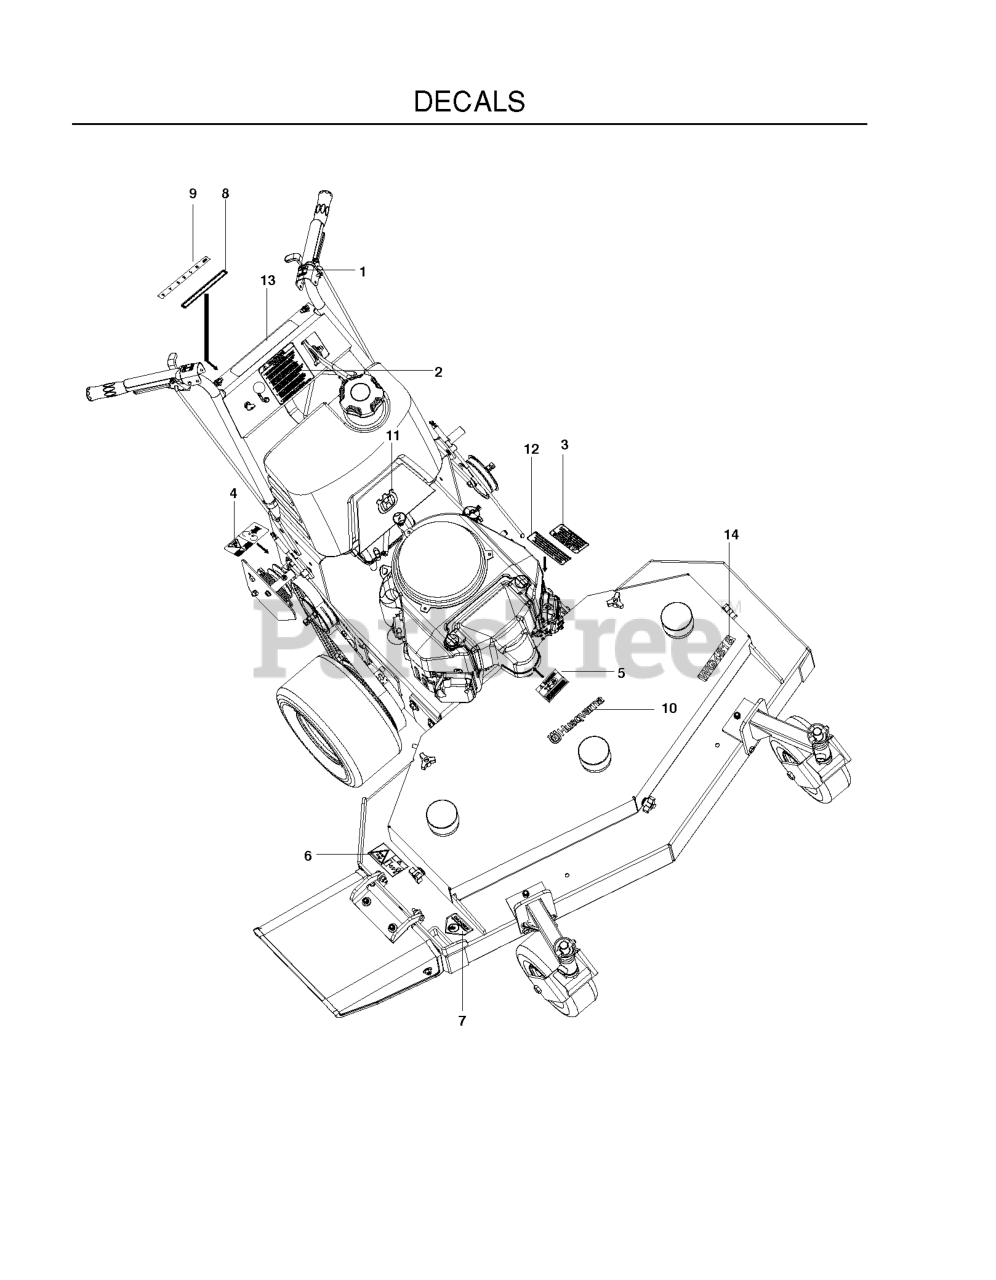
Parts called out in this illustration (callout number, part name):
1	DECAL, THUMB LATCH
2	DECAL, OPERATION
3	DECAL, PROP. 65
4	DECAL, BELT DRIVE
5	DECAL, EXHAUST
6	DECAL, EURO SEVERING
7	DECAL, CPSC
8	DECAL, CLUTCH
9	DECAL, SHIFTER
10	RP.DECAL.BADGE.170MM.TEXTLOGO
11	DECAL.AUGER.HUSQ.CROWN.SNOW
12	DECAL, WARNING SPARK ARRESTOR
13	DECAL, OPERATING
14	DECAL, WG3613
